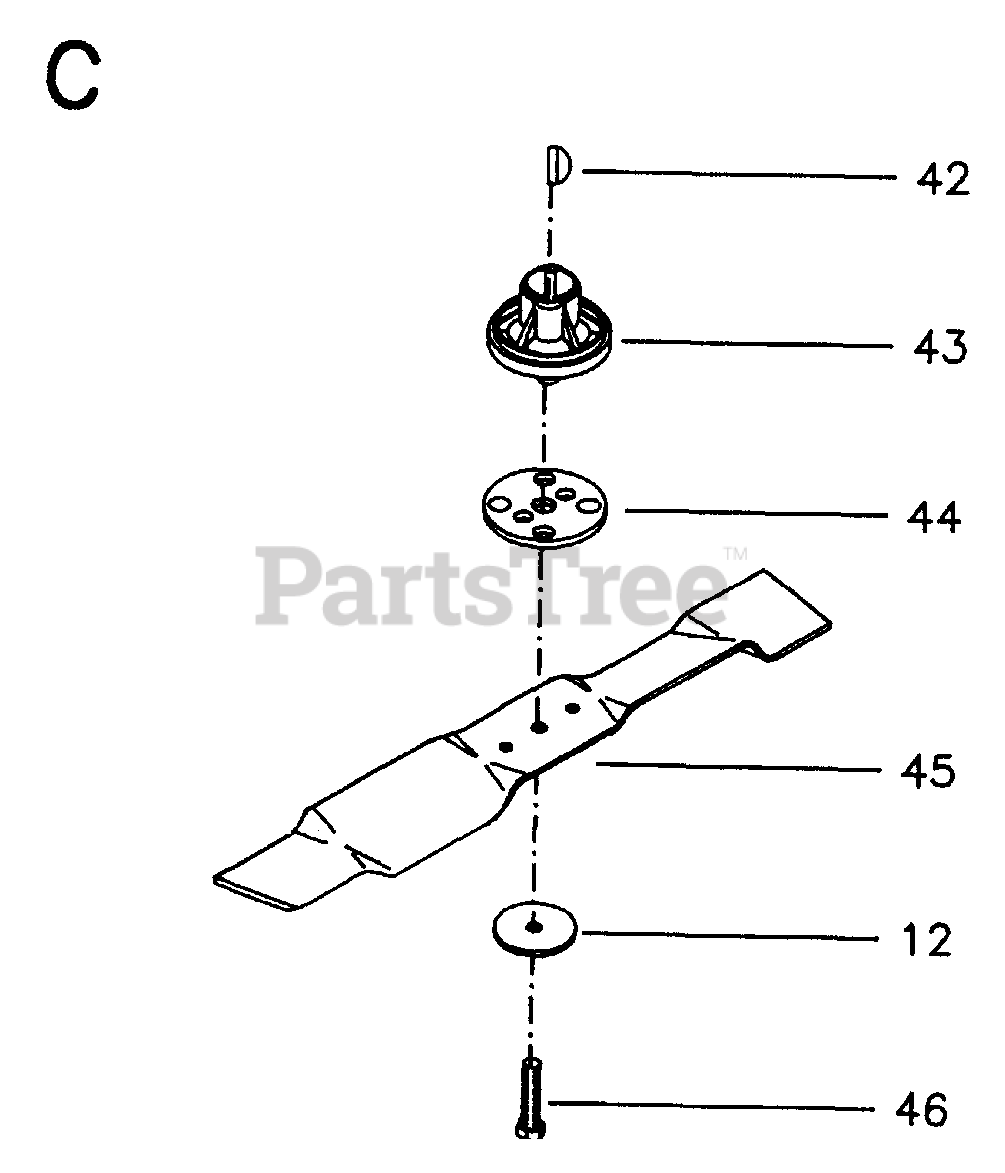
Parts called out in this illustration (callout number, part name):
42	WOODRUFF KEY
43	BLADE ADAPTER
44	STEEL PLATE ADAPTER
45	BLADE
